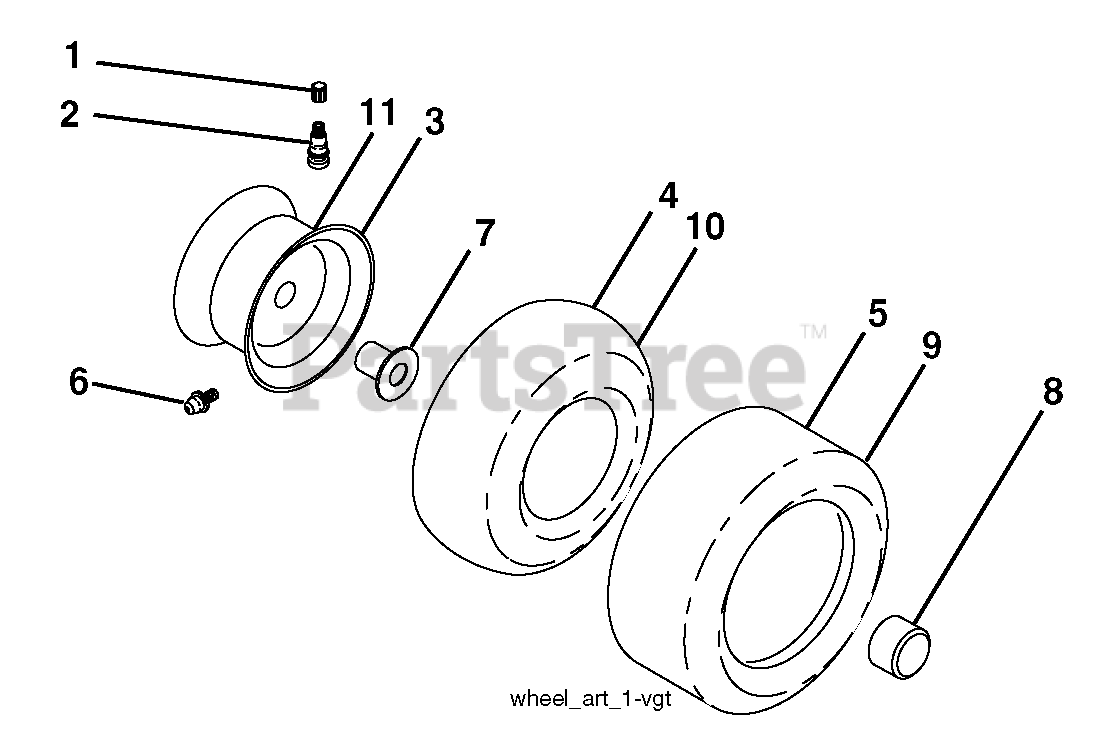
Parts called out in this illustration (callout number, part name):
1	Cap, Valve, Tire
2	Stem, Valve
3	Rim Assembly, Front
4	Tube, Front
5	Tire, Front
6	Fitting, Grease
7	Bearing, Flange
8	Cap, Axle
9	Tire, Rear
10	Tube, Rear
11	Rim Assembly, Rear
11	Sealant, Tire (10 oz. Tube)
